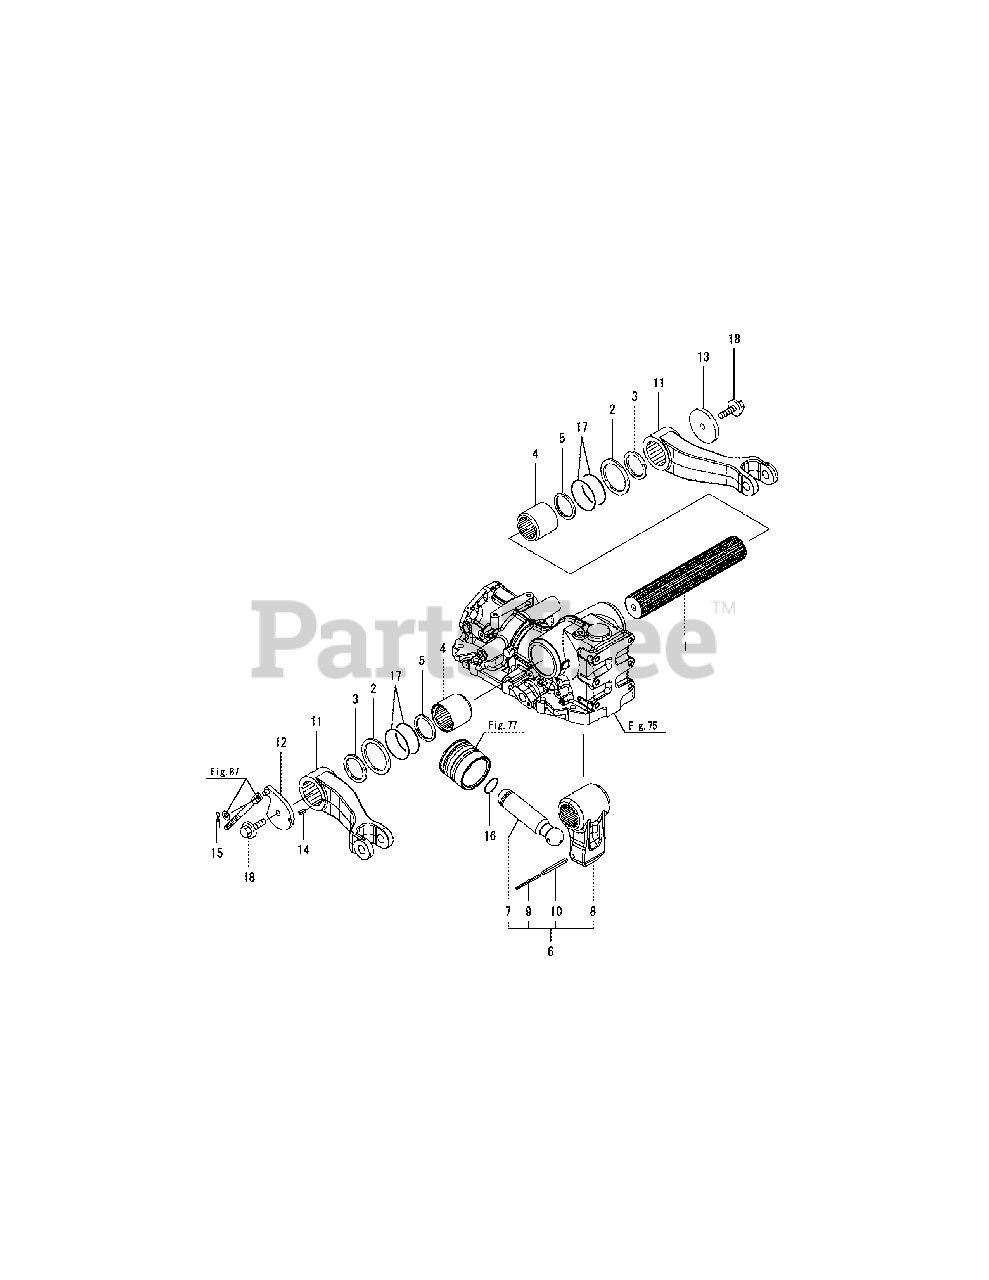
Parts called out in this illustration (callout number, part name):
2	WASHER, 65X82X2
4	SLEEVE, LIFT SHAFT
5	SEAL, SPLINE SHAFT
6	CRANK CMP, LIFT
9	SPRING PIN 5X70
10	SPRING PIN 8X70
12	PLATE, P FEEDBACK
14	SPRING PIN 6X16
15	COTTER PIN 2.0X20
16	O-RING 1A P-36.0
17	O-RING 1A G-65.0
18	BOLT M12X 30 PLATED
